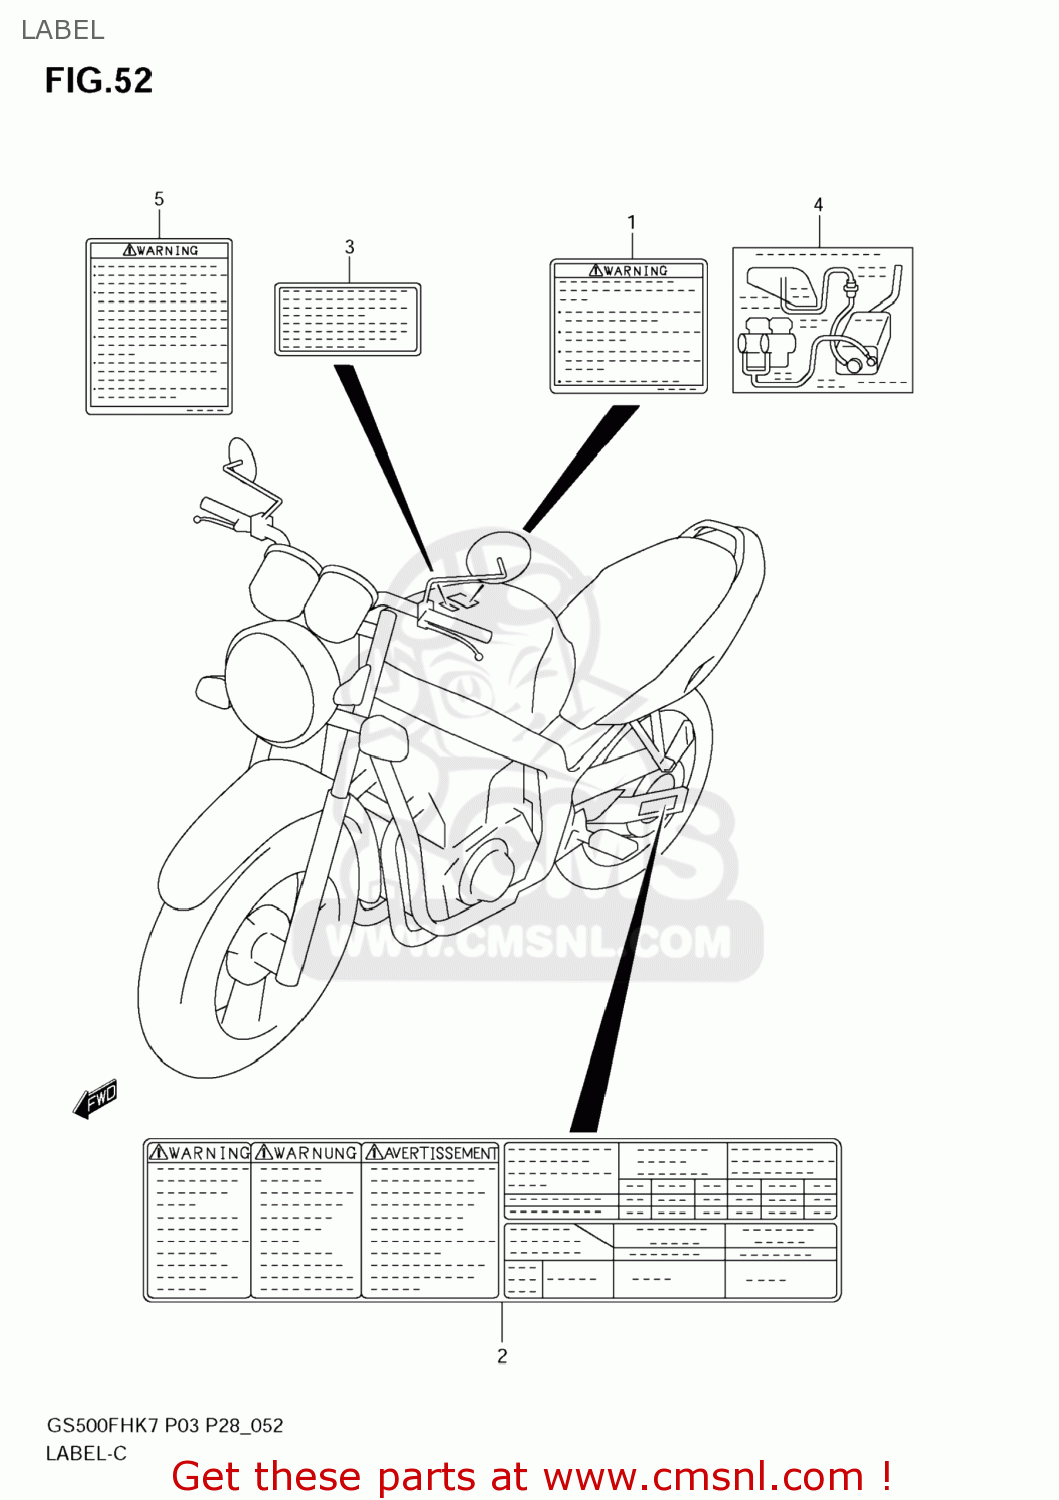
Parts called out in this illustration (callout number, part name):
1	LABEL,GENERAL WARNING
2	LABEL, TIRE E3, E33
3	LABEL,MANUAL NOTICE
4	LABEL,HOSE ROUTING
5	LABEL,SCREEN
6	OM GS500FK9
